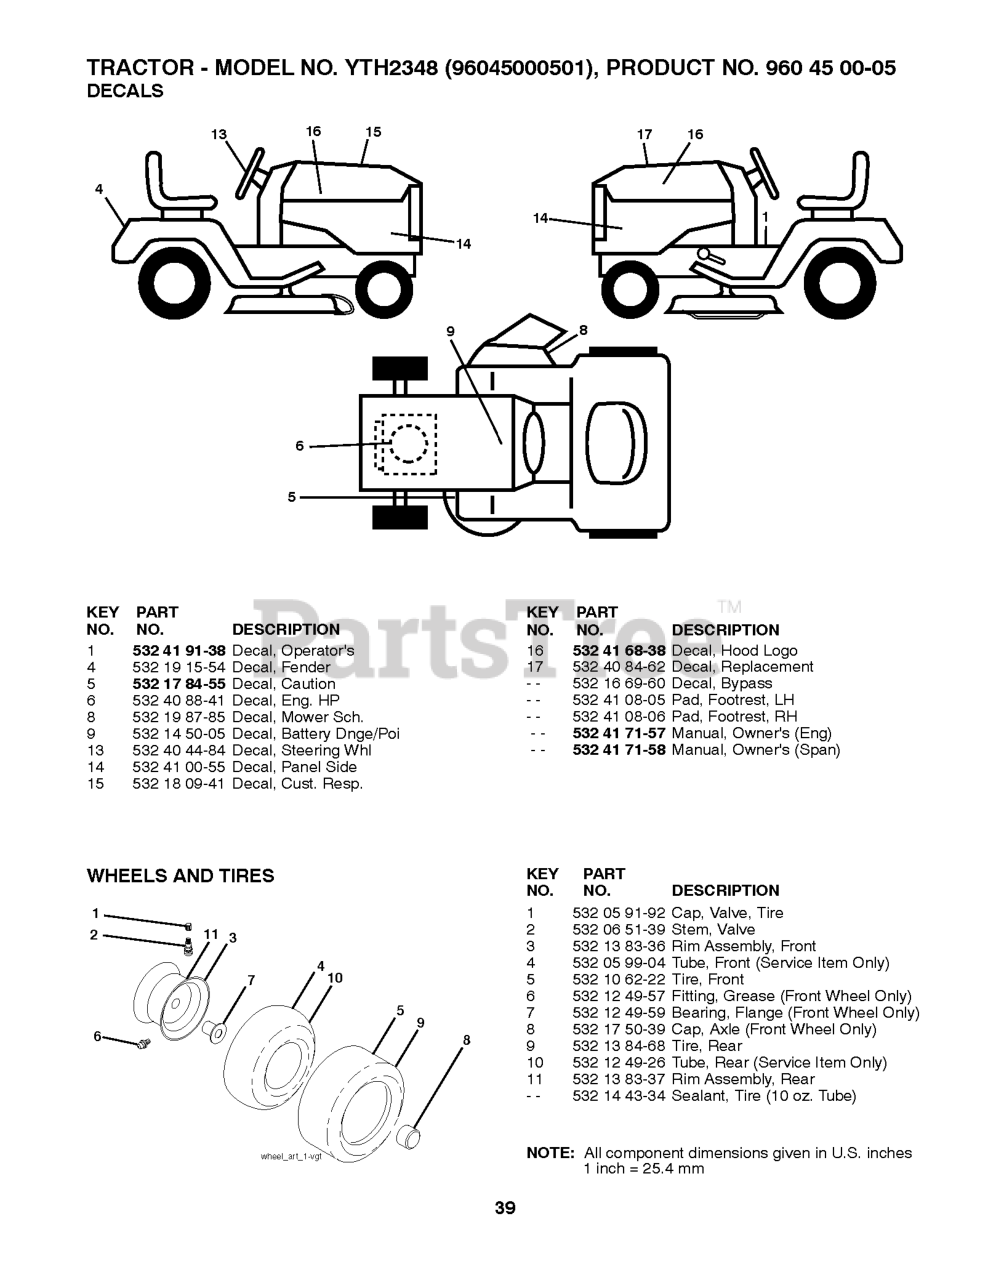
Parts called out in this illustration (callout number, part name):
1	DECAL.FENDER.WARNING.ENG
4	DECAL.FENDER
5	DECAL.MOWER
6	DECAL, ENG. HP
8	DECAL.MOWER.SCH.48/54
9	DECAL BTRY SYMBOLS
13	DECAL.WHEEL.STRG.LGN.H
14	DECAL, PANEL SIDE
15	DECAL HOOD CUST. RESP.
16	DECAL.HOOD.LOGO.HUSQVARNA
17	DECAL.RPL.BS.22INTK/HY/48E.TLT
